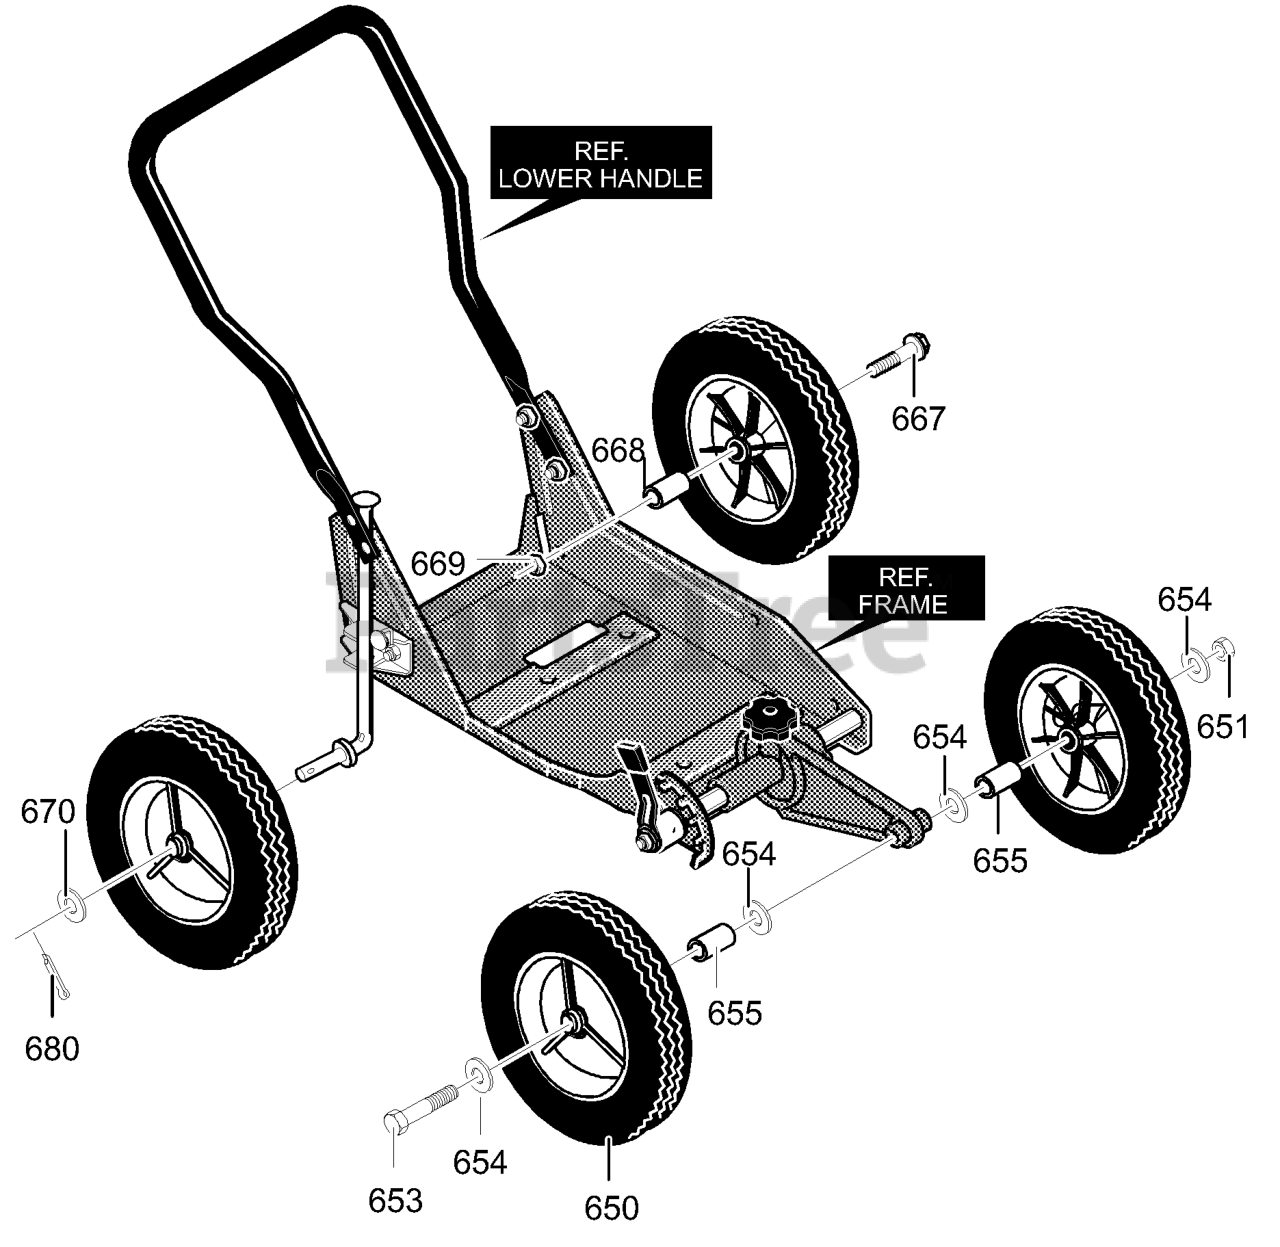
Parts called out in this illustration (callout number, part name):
650	Tire & Rim
651	Nut, 5/16-18
653	SCREW, 5/16-18 x 4.50
654	Flatwasher
655	Spacer, Sleeve
667	Bolt, SHH 3/8-16
668	Spacer, Sleeve
669	Nut, 3/8-16
670	Flatwasher
680	Cotter Pin
